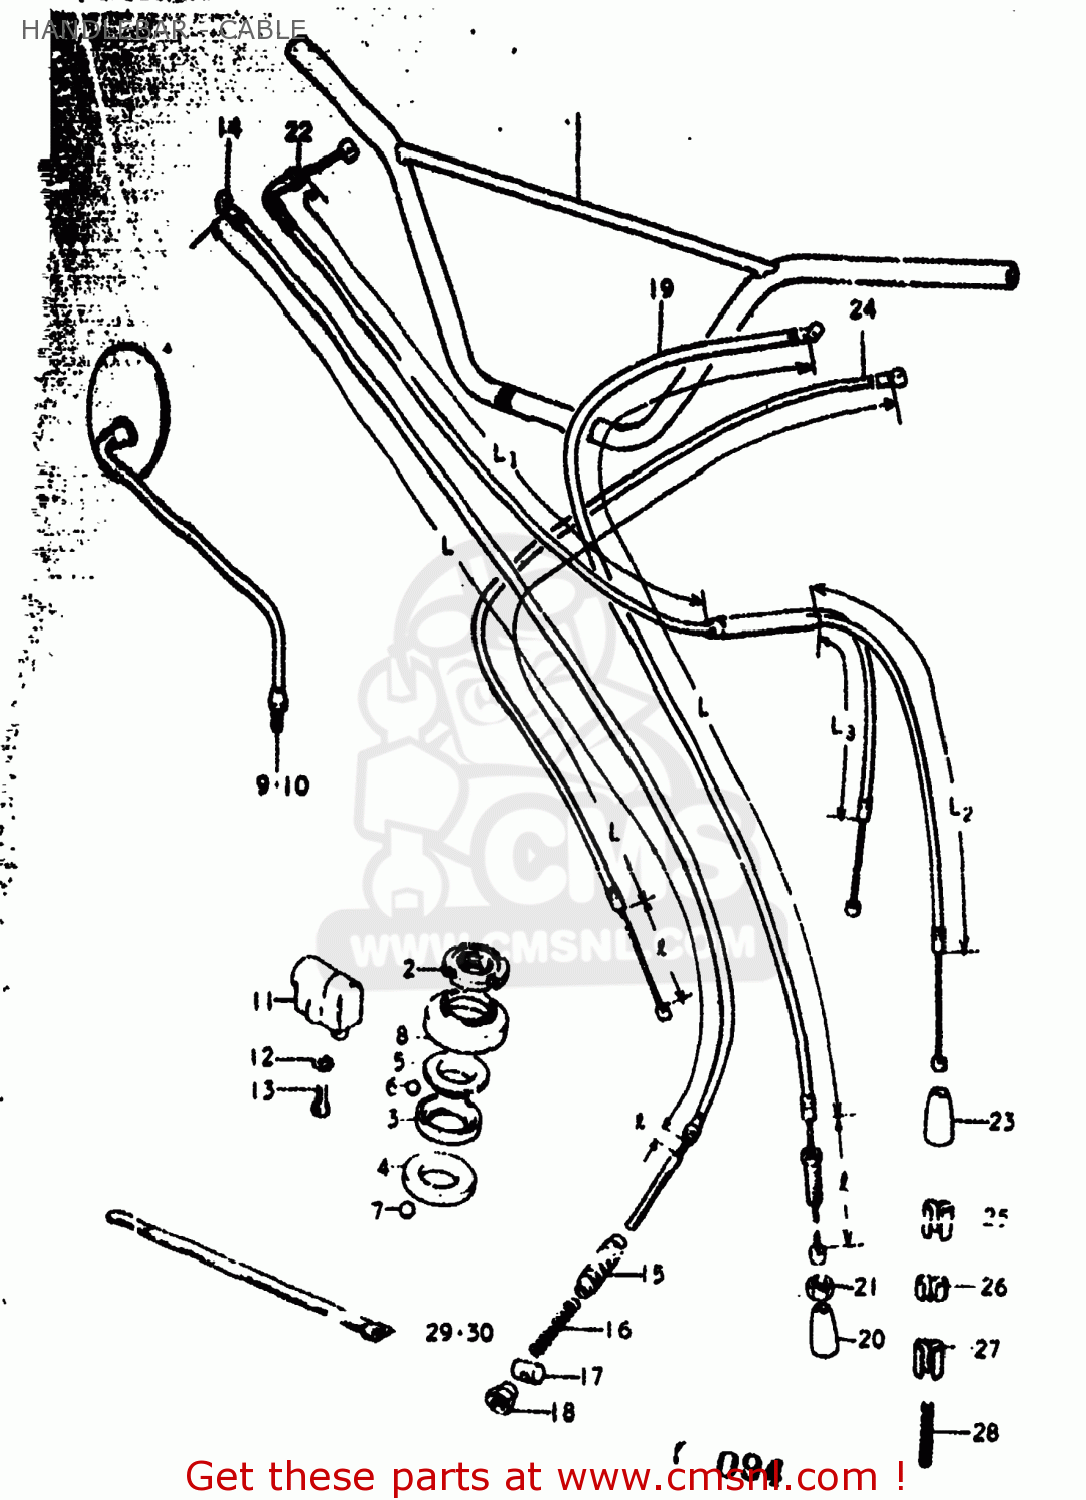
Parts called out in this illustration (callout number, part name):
1	HANDLEBAR
2	NUT,STEERING STEM(25X44X10)
3	RACE,STEERING INNER UPR
4	LACE,STEERING INNER LWR
5	RACE,STEERING OUTER UPR
6	BALL
7	BALL
8	DUST SEAL,STEERING UPR
9	MIRROR ASSEMBLY,RIGHT
10	MIRROR ASSEMBLY,LEFT
11	LOCK ASSY,STEERING
12	LOCK WASHER
13	Screw
14	CABLE ASSEMBLY,FRONT BRAKE
15	SEAL,DUST(7X16X75)
16	SPRING
17	PIN,10X19
18	NUT
19	CABLE ASSY,CLUTCH
20	SEAL,DUST(7X18X30)
21	NUT
22	CABLE ASSEMBLY,THROTTLE
23	SEAL,DUST(7X18X30)
24	CABLE COMP,STARTER
25	CLIP
26	CLIP
27	CLAMP
28	PROTECTOR,CABLE
29	CLAMP
30	CLAMP(L:120)
